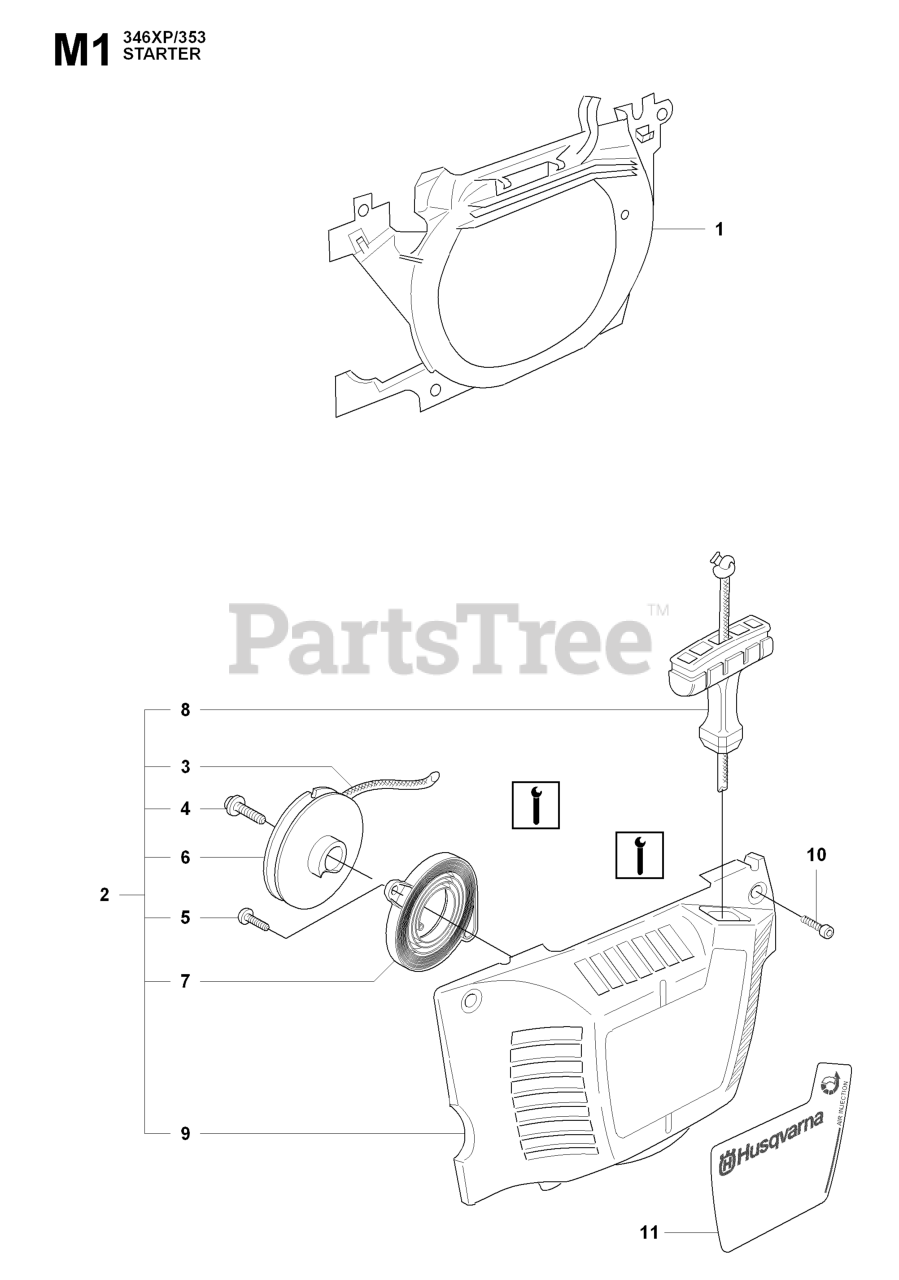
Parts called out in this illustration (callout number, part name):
1	AIR CONDUCTOR
2	STARTER HOUSING ASSY.
3	STARTER ROPE
6	PULLEY
7	RETURN SPRING
8	STARTER HANDLE
9	STARTER HOUSING
10	SCREW.CIHPANMO M5X19 10.9
11	DECAL
